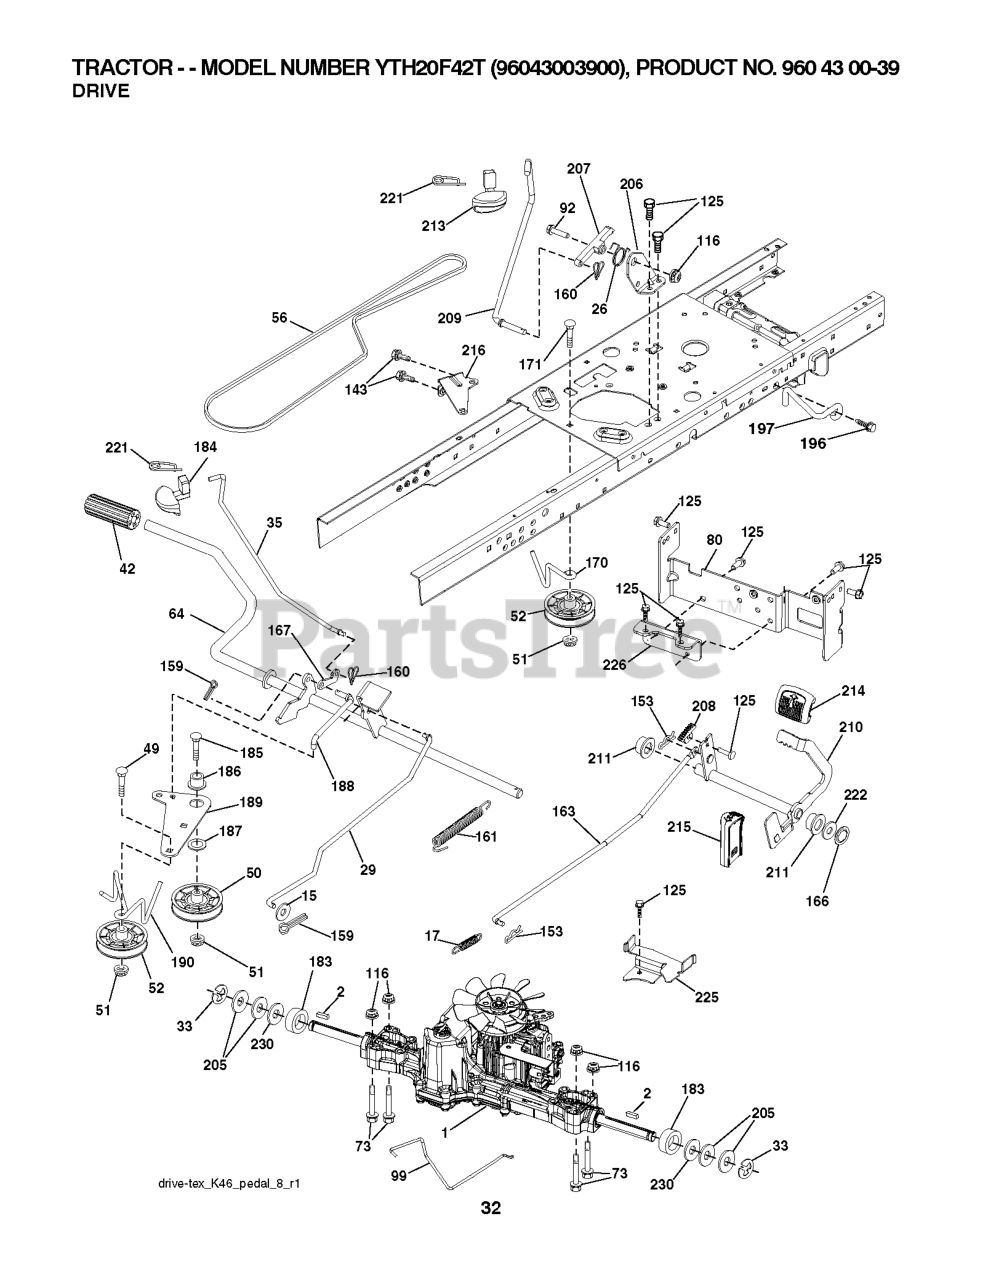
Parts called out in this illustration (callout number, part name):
1	TRANSAXLE, TUFFTORQ K46
2	SQUARE KEY
15	WASHER
17	SPRING.BRAKE.K46.GREEN
26	SPRING.RETURN.CRUISE
29	ROD.BRAKE.K46
35	ROD.BRAKE.PARKING.GT.H
42	PEDAL COVER T
50	IDLER.FLAT.910.OFFSET
51	NUT LOCK FLG 3/8-16 UNC
52	IDLER.V-GROOVE.910.OFFSET
56	V-BELT.MOWER.92.40.42/K46
64	SHAFT.ASM.PEDAL.BRK.CNTR
73	BOLT HEX 5/16-18 GR 5
80	STRAP TORQUE.ASM.K46/18"TEX
92	BOLT
99	ROD.SPRING.BYPASS.K46.LT.Z
116	NUT LOCK HEX FLANGE 5/16-18
125	SCREW
143	Screw 5/16-18 x 1/2 Hex, Self Tapping 5/16-18 x 1/2
153	RETAINER M
159	COTTER PIN
160	RETAINER CLIP
161	SPRING, RETURN LT
163	ROD.CONTROL.PEDAL.K46
166	NUT.PUSH.625.2006
167	LATCH.BRAKE.SPRING
170	KEEPER.V-IDLER.CENTER.
183	SPACER AXLE
184	HANDLE.PARKG.BRK.HUSQ X667
186	SPACER.RETAINER
187	WASHER 12/32X2X10GA
188	RP.LINK.CLUTCH.GROUND.DRIVE
189	BELLCRANK.GROUND.DRIVE.TEX.
190	KEEPER.BELLCRANK.DRIVE
196	SCREW 3/8-16X1
197	LINK.CLUTCH.ANIT-ROTAT
206	BRKT.MOUNT.LATCH.CRUIS
207	LATCH.CONTROL.CRUISE
208	GEAR.SECTOR.CONTROL.CR
209	ROD.CONTROL.CRUISE.GT.
210	ROCKER.ASM.PEDAL.CONTR
211	BEARING.NYLON
213	KNOB.CONTROL.CRUSIE.HU
214	PEDAL.FORWARD.TEX.GT.4
215	PEDAL.REVERSE.TEX.GT.4
216	BRACKET.PULLEY.IDLER.W/TEX
221	RETAINER.SPRING.CLIP.H
222	WASHER 21/32 X 1-1/4 X 10 GA.
225	KEEPER.BELT.TRANSAXLE.K46
226	BRACKET.MOUNT.TORQUE.K46.TLT
230	WASHER.HARDENED
